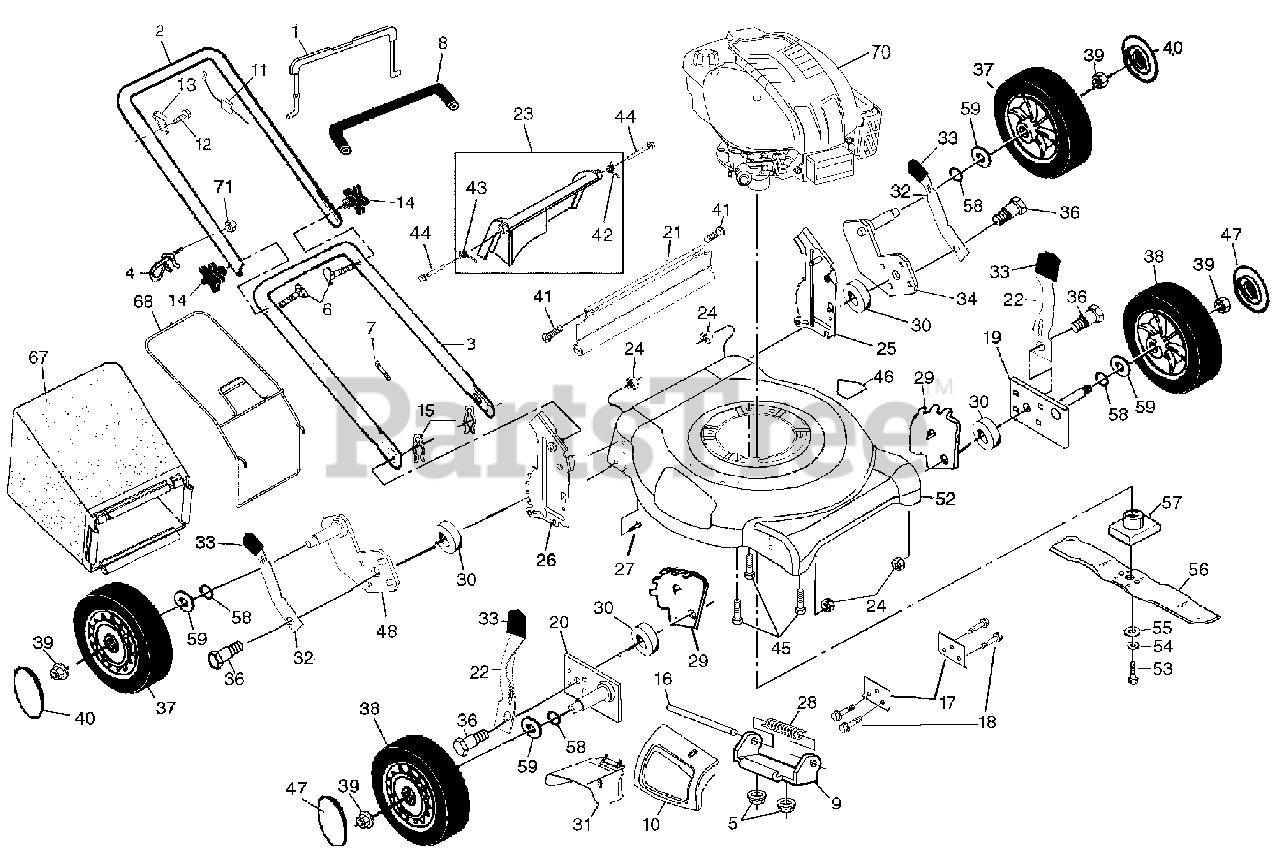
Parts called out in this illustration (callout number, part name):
1	Control Bar
2	Upper Handle, with Grip
3	Lower Handle
4	Rope Guide
5	Locknut 1/4-20
6	Handle Bolt
7	Wire Tie
8	Grip, Foam
9	Hinge Bracket
10	Mulcher Door
11	Engine Zone Control Cable
12	Hex Washer Head Screw
13	Up-Stop Bracket
14	Handle Knob
15	Hairpin Cotter
17	Support Bracket
19	Axle Arm Assembly - LF
20	Axle Arm Assembly - RF
21	Rear Skirt
22	Selector Spring - Front
23	Rear Door Assembly Kit
24	Locknut 5/16-18
25	Handle Bracket Assembly (Left)
26	Handle Bracket Assembly (Right)
27	Screw 1/4-20 x 3/8
28	Hinge Spring
29	Wheel Adjusting Bracket - Front
31	Clip on Discharge Guard
32	Selector Spring - Rear
33	Selector Knob
34	Axle Arm Assembly - LR
36	Shoulder Bolt 5/16-18
37	Wheel Assembly, Rear
38	Wheel Assembly, Front
39	Flanged Locknut
41	Hinge Screw
42	Spring (LH)
43	Spring (RH)
45	Hex Head Thread Rolling Screw 3/8-16 x 1
46	Danger Decal
47	Hubcap
48	Axle Arm Assembly - RR
52	Housing Assembly
53	Hex Head Screw 3/8-24 x 1-3/8 Grade 8
54	Helical Lockwasher
55	Hardened Washer
56	21" Blade
57	Blade Adapter
58	O-Ring
59	Washer, Flat 3/8
67	Grass Bag
68	Frame, Grass Bag
71	Nut, Hex 1/4-20
